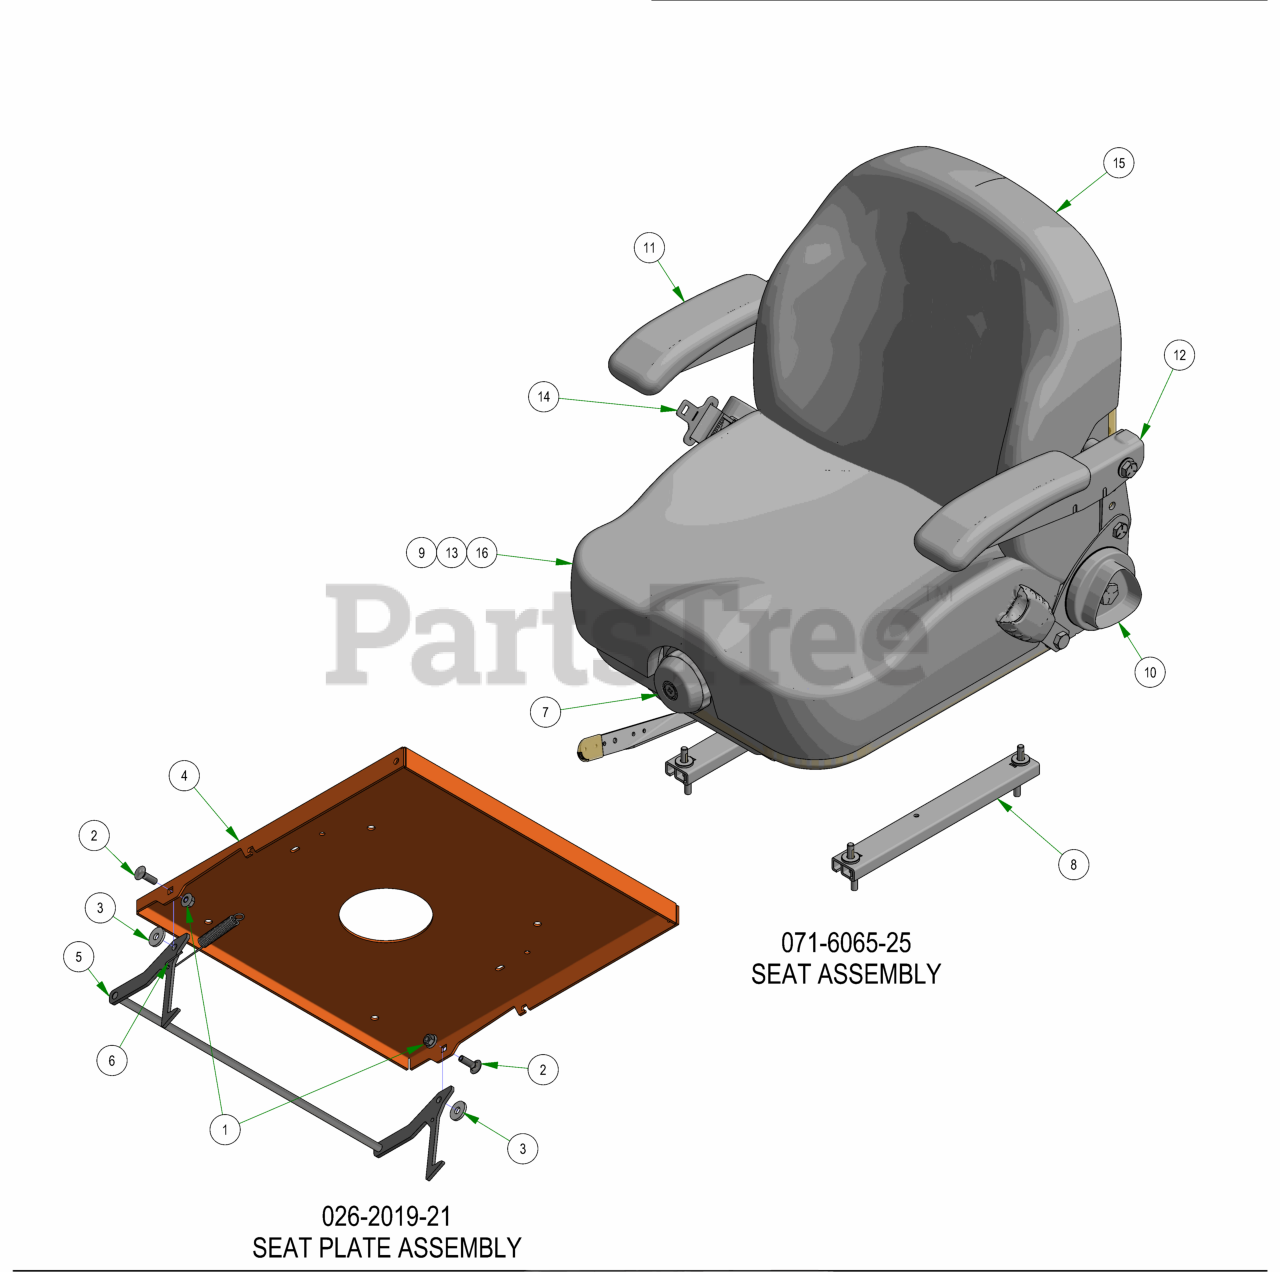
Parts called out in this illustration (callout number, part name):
1	5/16-18 NYLON INSERT FLANGE LOCKNUT ZINC
2	5/16-18 X 1 CARRIAGE BOLT (GR.8) ZINC
3	.360 ID X .983 OD X .120 THICK FLAT WASHER NYLON
4	R-SERIES SEAT PLATE
5	Seat Latch Rod Assembly
6	Brake Spring
7	Weight Adjust Indicator Knob Assy
8	4" Single Locking Track Kit
9	Delta Plunger Switch - N.O.
10	Recliner Adjustment Knob-New
11	RH Armrest-Selfskin Front Adj
12	LH Armrest-Selfskin Front Adj
13	Bellows w/Hardware
14	2" Retractable Belt Kit w/Spacers
15	Back Cover, 2025 Suspension Seat
16	Cushion Cover, 2025 Suspension Seat
